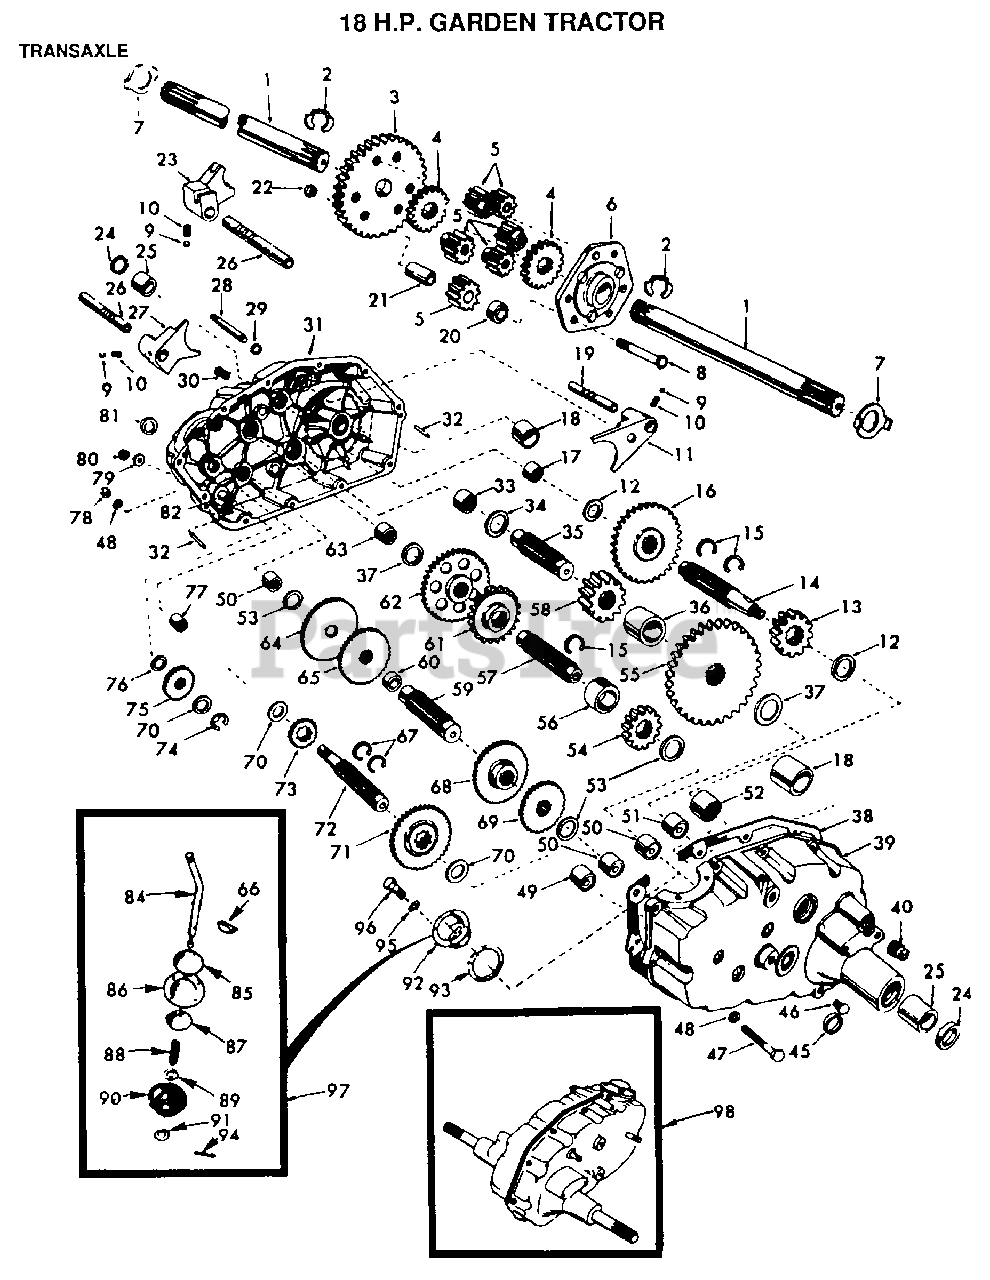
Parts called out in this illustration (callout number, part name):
2	KLIP RING
3	FINAL GEAR T
4	DIFF GEAR T
5	DIFF PINION T
6	DIFF CARRIER T
8	BOLT
11	SHIFT FORK T
12	WASHER .T
13	RED PINION T
14	GEAR SHAFT T
15	SNAP RING T
16	GEAR T
17	"T, BEARING"
18	BEARING
19	SHAFT
20	SPACER T
21	PINION RS
22	GRIPCO NUT
23	SHIFT FORK T
24	OIL SEAL STD
25	BRNG. T
27	FORK T
28	SHIFT SHAFT
29	SEAL T
30	VALVE M
31	GEARCASE RH
32	PIN T
33	NEEDLE BRNG T
34	RACE T
35	GEAR SHAFT T
37	RACE T
38	GASKET
39	GEARCASE LH
40	PLUG PIPE
45	SEAL T
47	HEX BOLT
49	"TI, BEARING"
50	NEEDLE BRNG T
51	NEEDLE BRNG T
52	"STD, BEARING"
53	BRNG RACE
54	RED PINION T
55	RED GEAR T
56	PINION SPACER T
57	GEAR SHAFT T
58	FINAL PINION T
59	GEAR SHAFT T
60	SPACER T
61	RED PINION T
62	RED GEAR T
63	RACE T
64	LOW SPEED GEA T
65	REVERSE GEAR T
66	KEY T
67	RING STD
68	INTERMED GEAR T
70	"T, BEARING"
71	CLUSTER GEAR T
72	INPUT SHAFT T
73	LO SPEED PINION T
75	IDLER GEAR T
76	WASHER T
77	BRNG T
78	NUT.HEX.5/16-18
79	WASHER T
80	NUT
81	SEAL STD
84	GEAR SHIFT LVR T
85	CAP T
86	COVER AND PIN T
87	GUIDE BALL T
88	SPRING TI
89	WASHER
90	SEAL T
91	WASHER
92	GEAR SHIFT GA T
93	GASKET T
94	COTTER PIN
95	LOCKWASHER
96	BOLT
